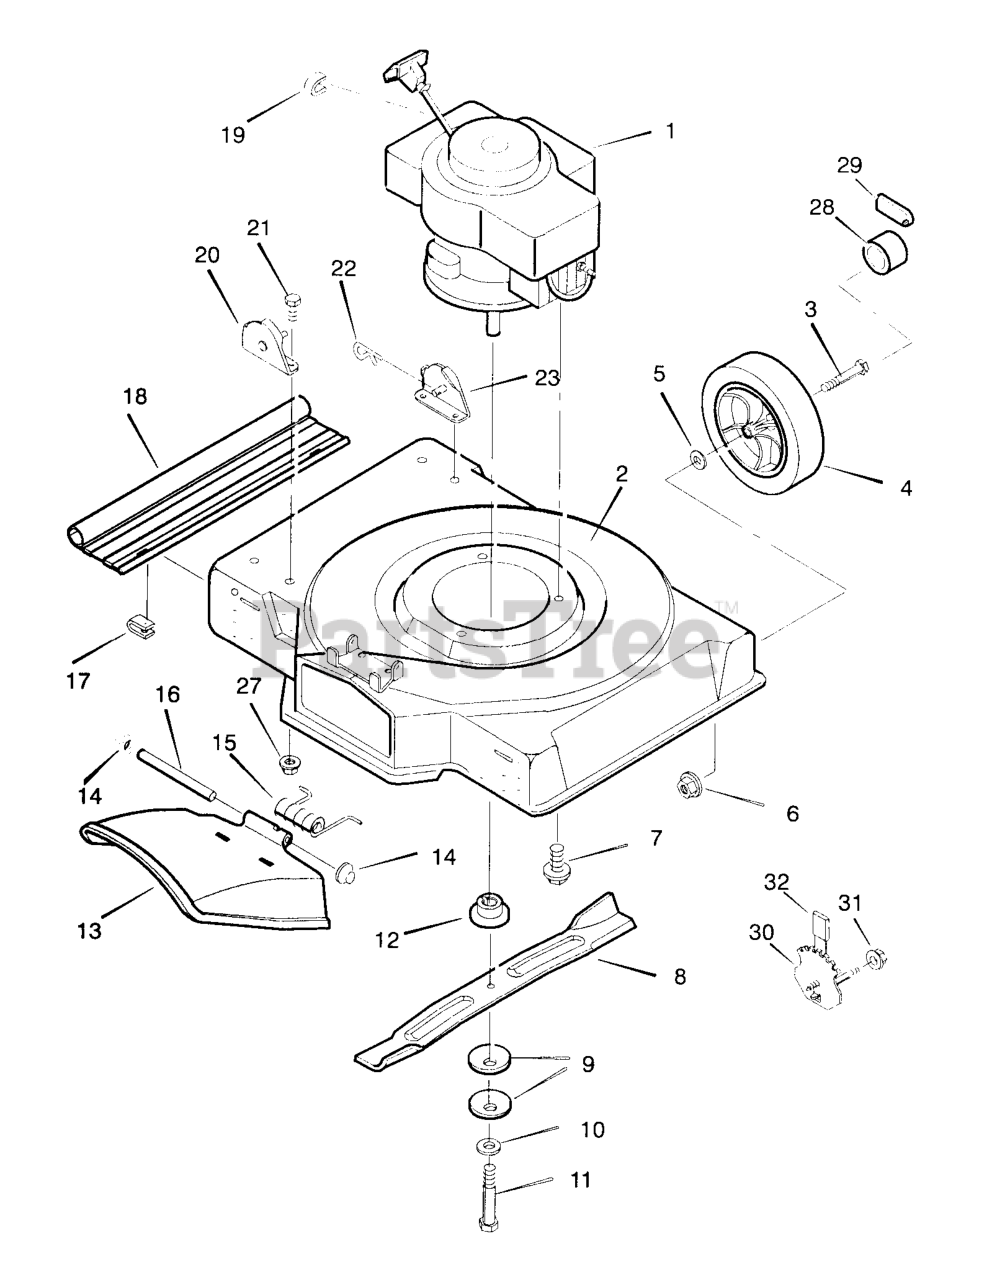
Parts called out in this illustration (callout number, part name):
1	Engine *
2	Housing
3	Bolt, Axle
4	Wheel and Tire *
6	Locknut, Flange
7	Bolt, Engine
9	Washer, Belleville
11	Bolt, Hex
12	Adapter, Blade
13	Deflector, Chute
14	Push- On Cap
16	Pin, Pivot
17	Retainer
18	Deflector, Rear
19	Stop, Rope
20	Bracket, Right Handle
22	Pin, Hair
23	Bracket, Left Handle
27	Nut
28	Hub Cap
29	WHEEL & TIRE ASSEMBLY, White, 8"
30	Adjuster, Height
31	Locknut, Flange
33	Plate, Mulcher
